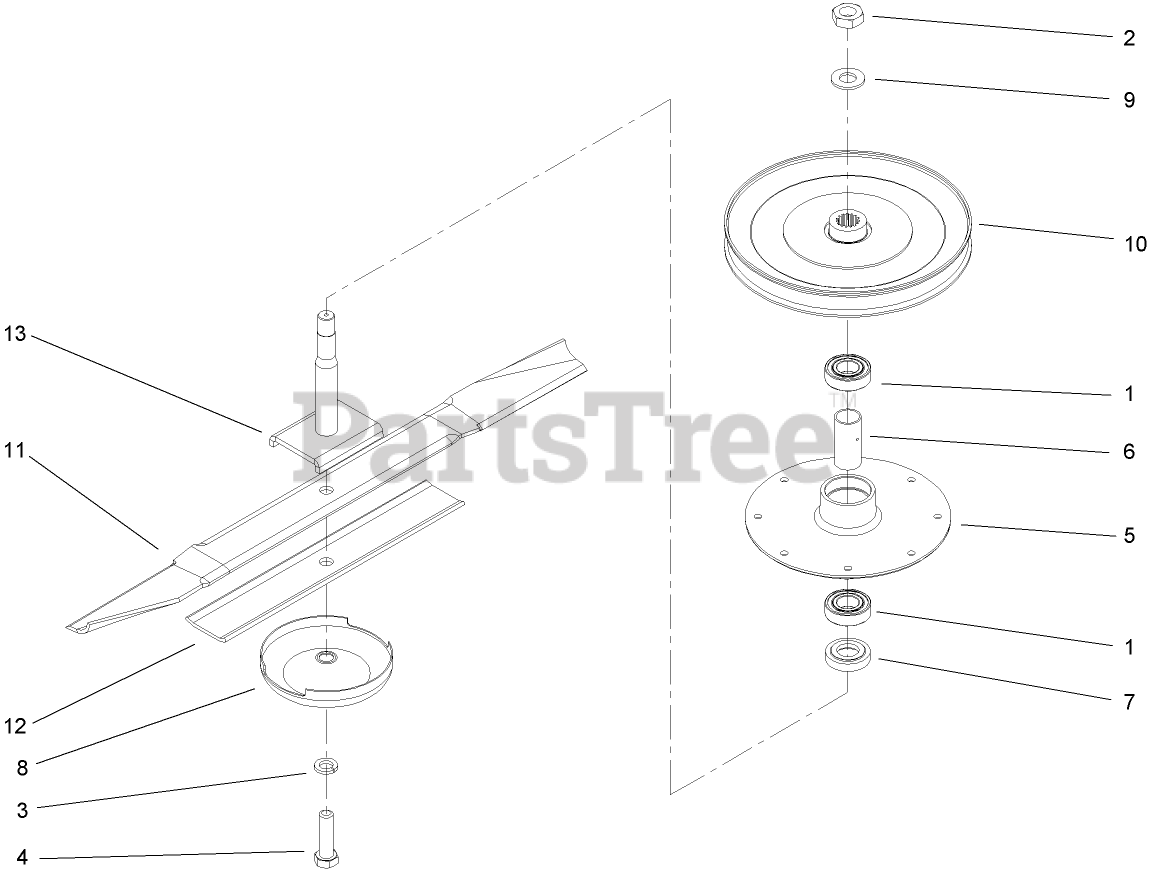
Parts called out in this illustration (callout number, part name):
1	BEARING-BALL
2	NUT-HEX
3	WASHER-LOCK/SP
4	SCREW-BLADE
5	HOUSING-SPINDLE
6	SPACER-BEARING
7	SPACER
8	CUP-SCALP, ANTI
9	Washer-Pinion
10	PULLEY ASM
11	BLADE-RECYCLER
12	SPACER-BLADE
13	SPINDLE SHAFT ASM
